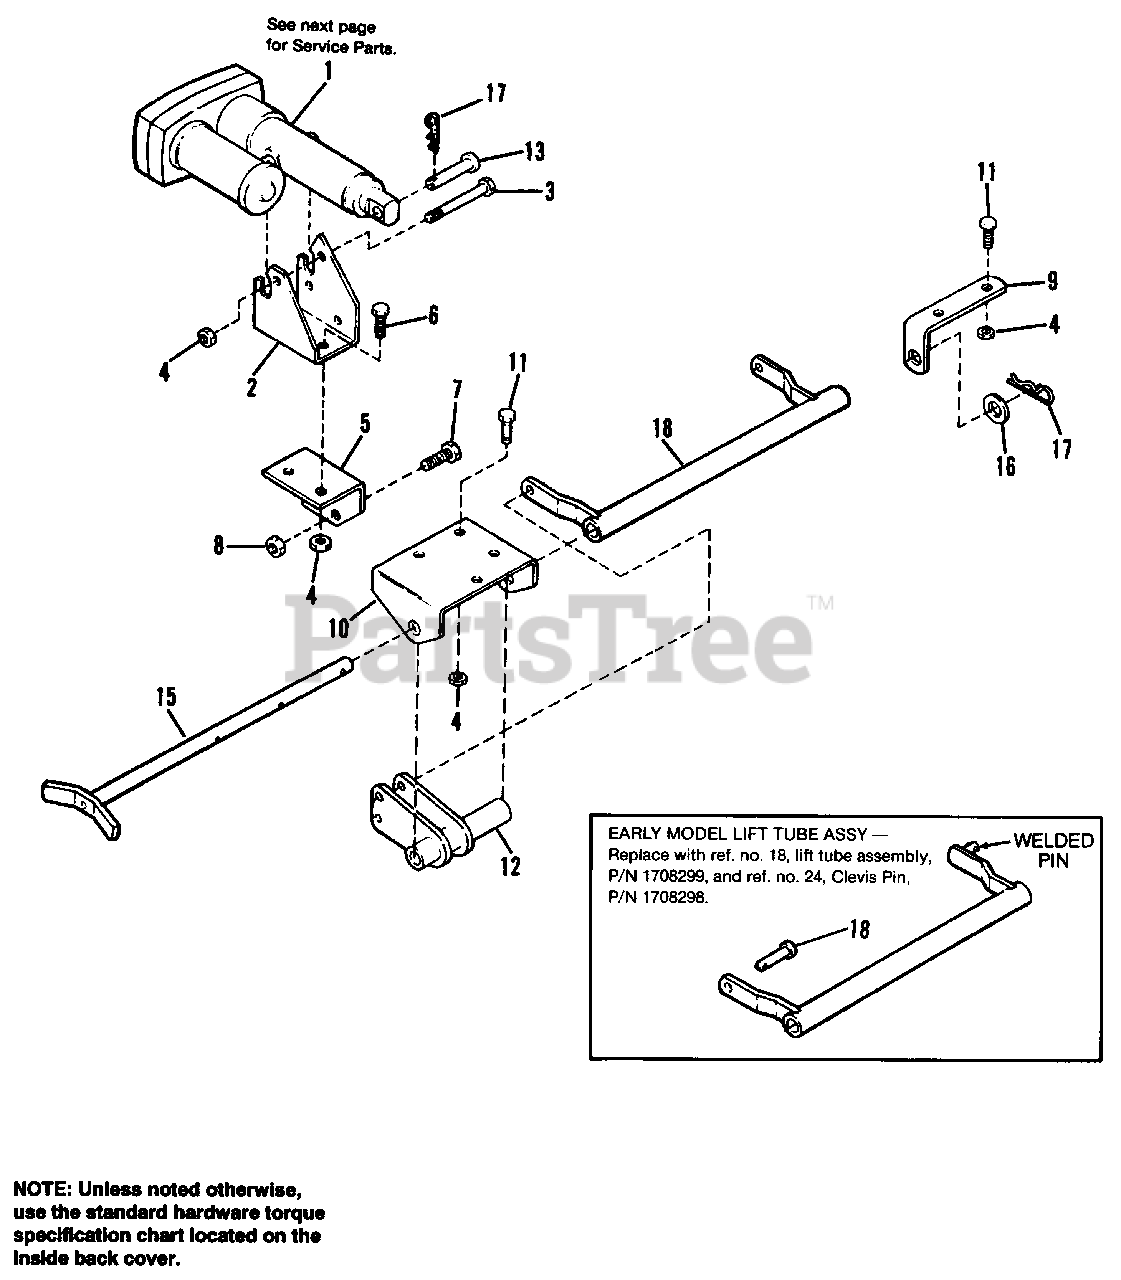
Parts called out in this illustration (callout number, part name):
1	POWER LIFT ASSY.
2	BRACKET, Actuator
3	CAPSCREW, Hex, 5/16-18 x 3-1/4
4	NUT, Hex, Lock, Esna, 5/16-18
5	SUPPORT, Actuator
6	CAPSCREW, Hex, 5/16-18 x 1
7	CAPSCREW, Hex, Whizlock, 3/8-16 x 1
8	NUT, Hex, Lock, Esna, 3/8-16
9	LIFT, Pivot Bracket
10	SUPPORT, Lift
11	CAPSCREW, Hex, 5/16-18 x 7/8
12	LIFT ARM ASSY.
13	PIN
14	LIFT TUBE ASSY.
15	SHAFT ASSY.
16	WASHER, Plain
17	CLIP, Hair Pin (Large)
